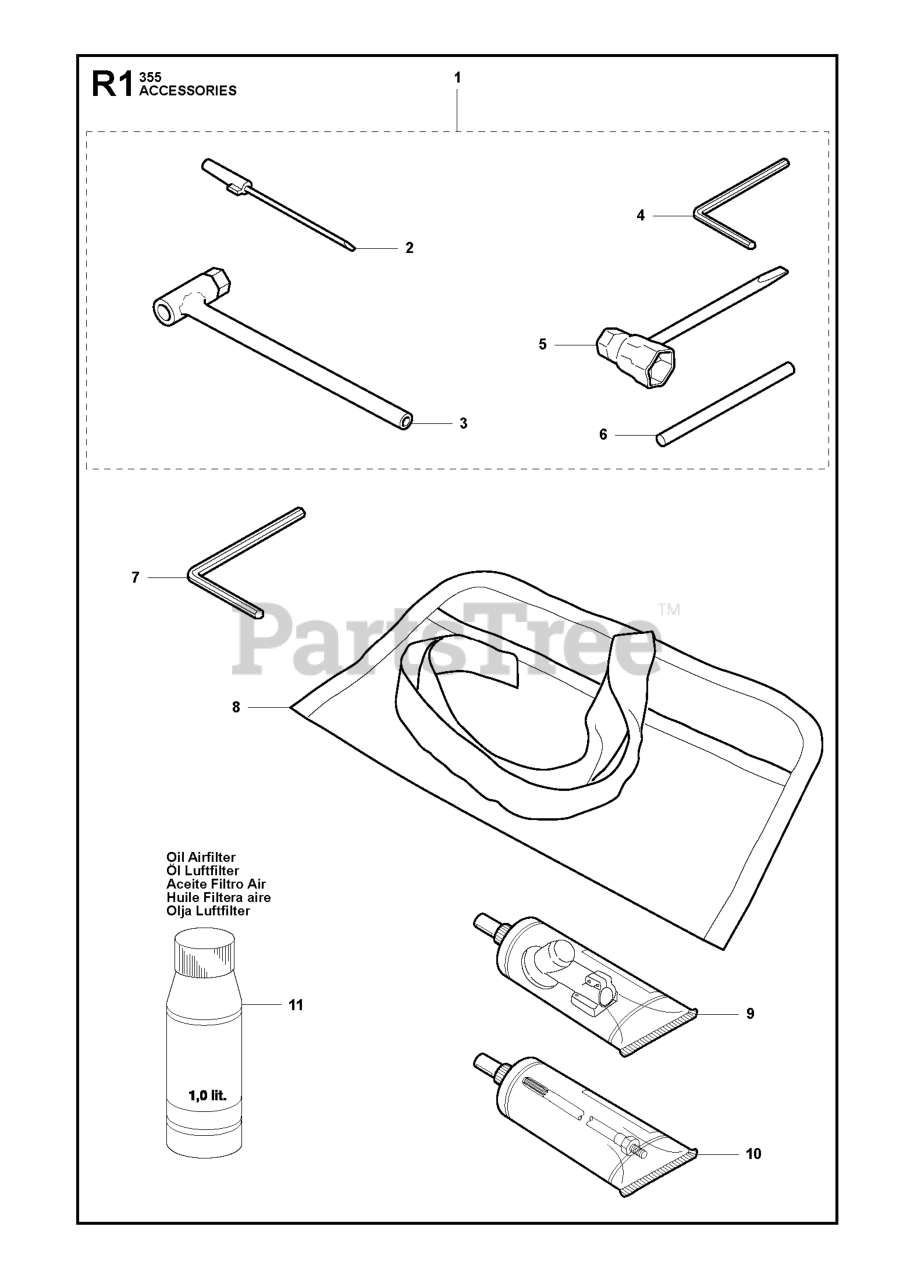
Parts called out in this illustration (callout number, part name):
1	RP ACCESSORY BAG
2	SCREWDRIVER
4	L-KEY WRENCH
5	COMBI TOOL
6	LOCKING PIN
7	KEY
9	BEVEL GEAR GREASE
10	DRIVE SHAFT GREASE (200 G)
11	Air Filter Oil 1l.
